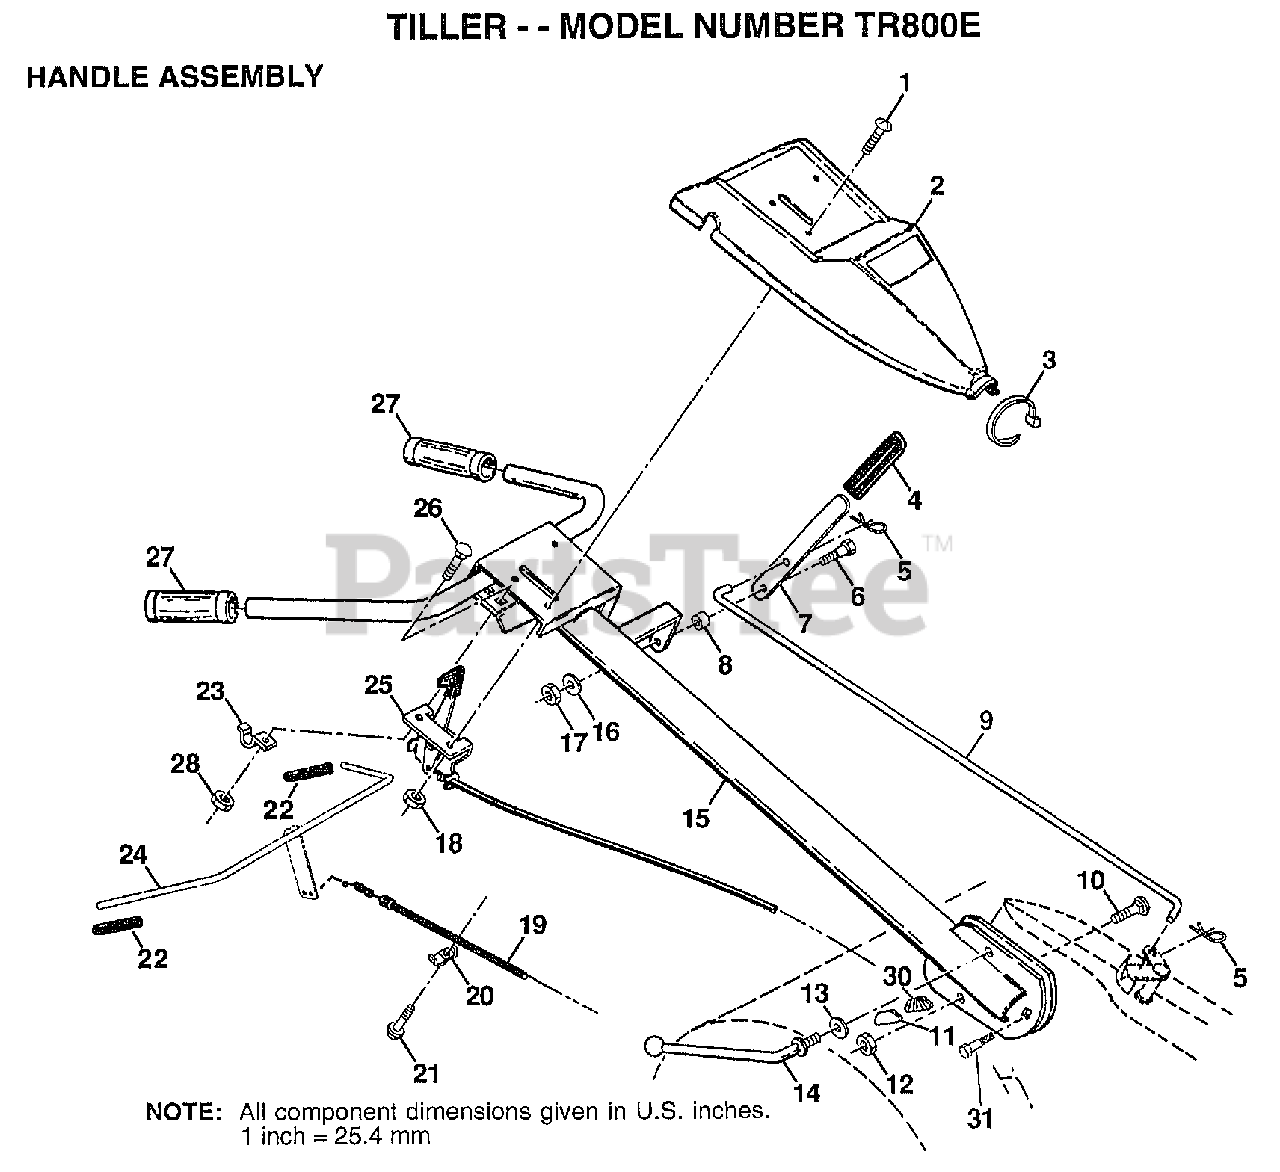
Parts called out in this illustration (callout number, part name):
1	SCREW.PNHD.10-24
2	"PANEL,CONT TI"
3	TIE CABLE CRT
4	GRIP T
6	SHOULDER BOLT ST
7	SHIFT HANDLE CRT
8	GROMMET CRT
9	ROD.SHIFT
10	BOLT D
11	LOCK CRT
12	LOCKNUT
13	WASHER CRT
14	LEVER LOCK CRT
16	LOCKWASHER
19	CABLE.CLUTCH
20	CONDIUT CLIP T
22	GRIP BAR CRT
24	BAR ASM CONTROL
25	CONTROL.THROTTLE
26	BOLT
28	NUT
30	LOCK.HANDLE
31	BOLT PIVOT
